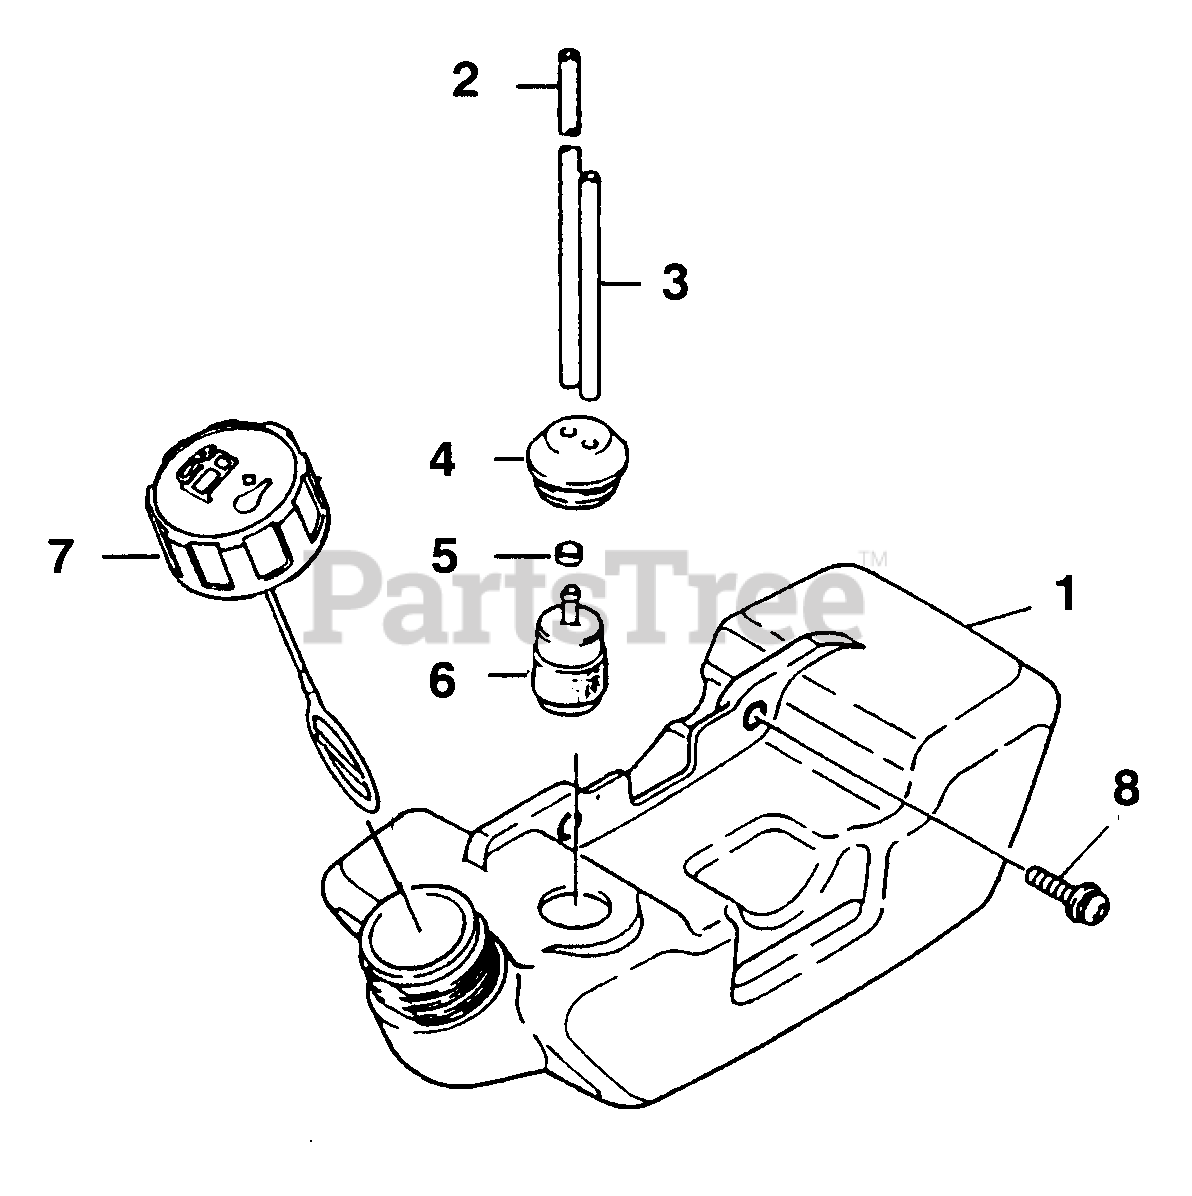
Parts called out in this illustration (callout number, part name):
1	Fuel Tank Assembly
2	Tube, Fuel
3	Tube, Fuel
5	Bushing
6	Filter, Fuel
7	Cap, Fuel Tank
8	Screw & Washer
